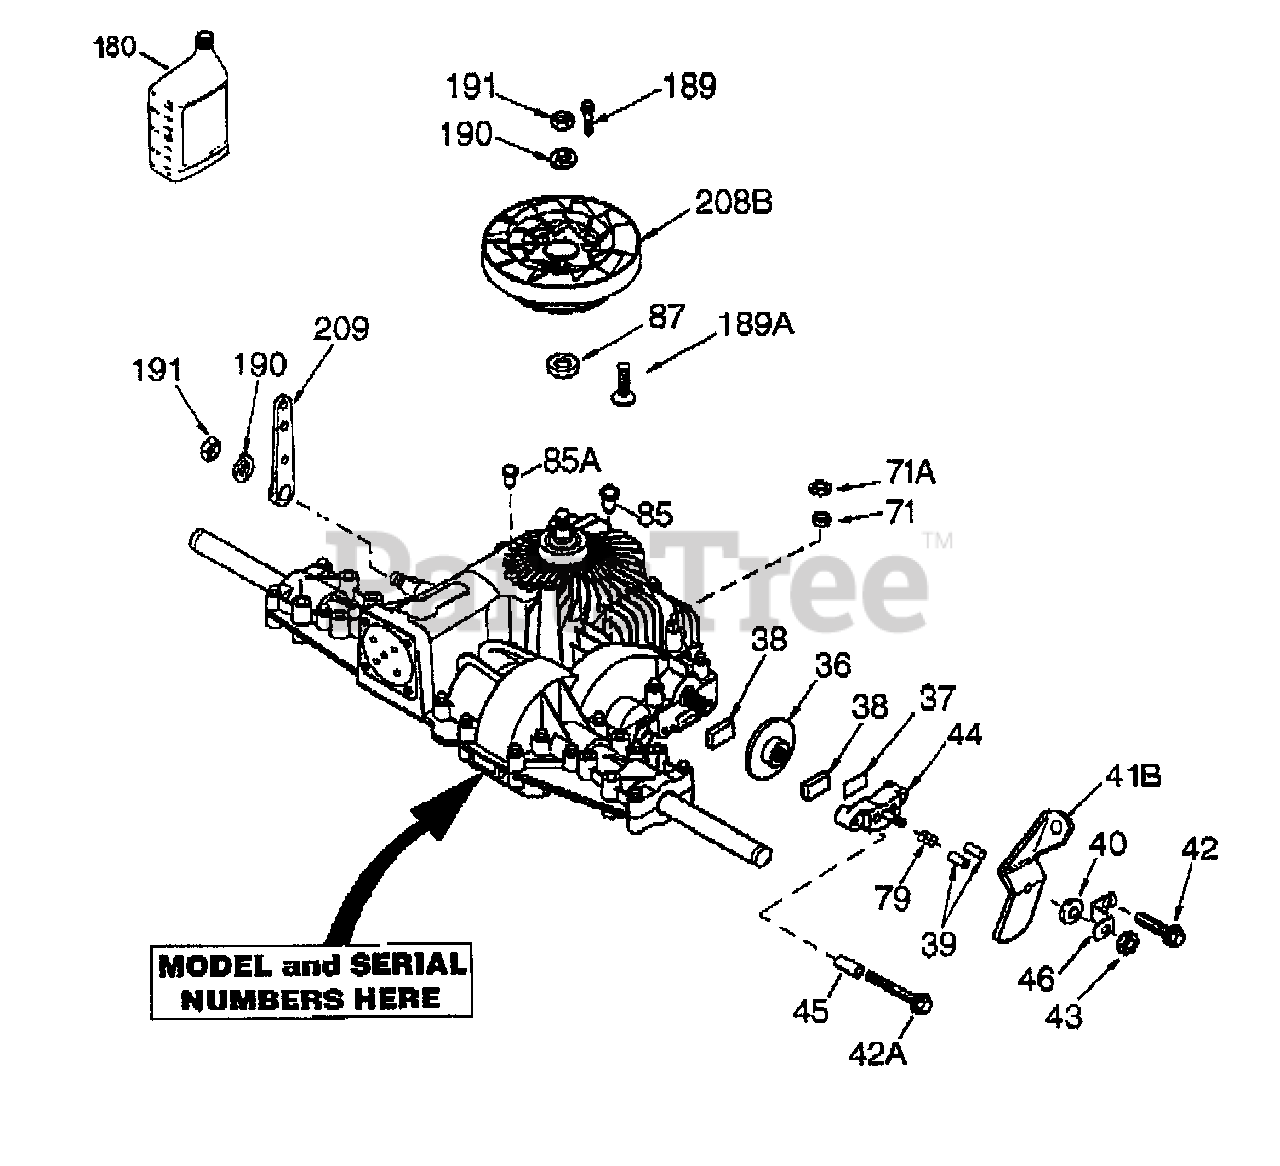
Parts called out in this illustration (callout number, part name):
36	Brake Disc
37	Brake Pad Plate
38	Brake Pad (pkg of 2)
39	Dowel Pin
40	Flat Washer
41B	Brake Lever
42	Screw, 1 /4-20 x 1-1 /4"
42A	Screw, 1 /4-20 x 2-1 /4"
43	Locknut, 5/16-24
44	Brake Pad Holder
46	Brake Lever Bracket
71	Square Cut Ring
71A	Pushnut, 9/16"
85	Oil Fill Plug
85A	Tube Plug, 3/8"
87	Oil Seal, 5/8"
180	Gear Oil 80W90
189	Drive Screw #6 x 1/2"
189A	Screw, 10-32 x 1/2"
190	Lockwasher
191	Nut, 7/16-20
208B	Fan/Coupling
209	Control Lever
